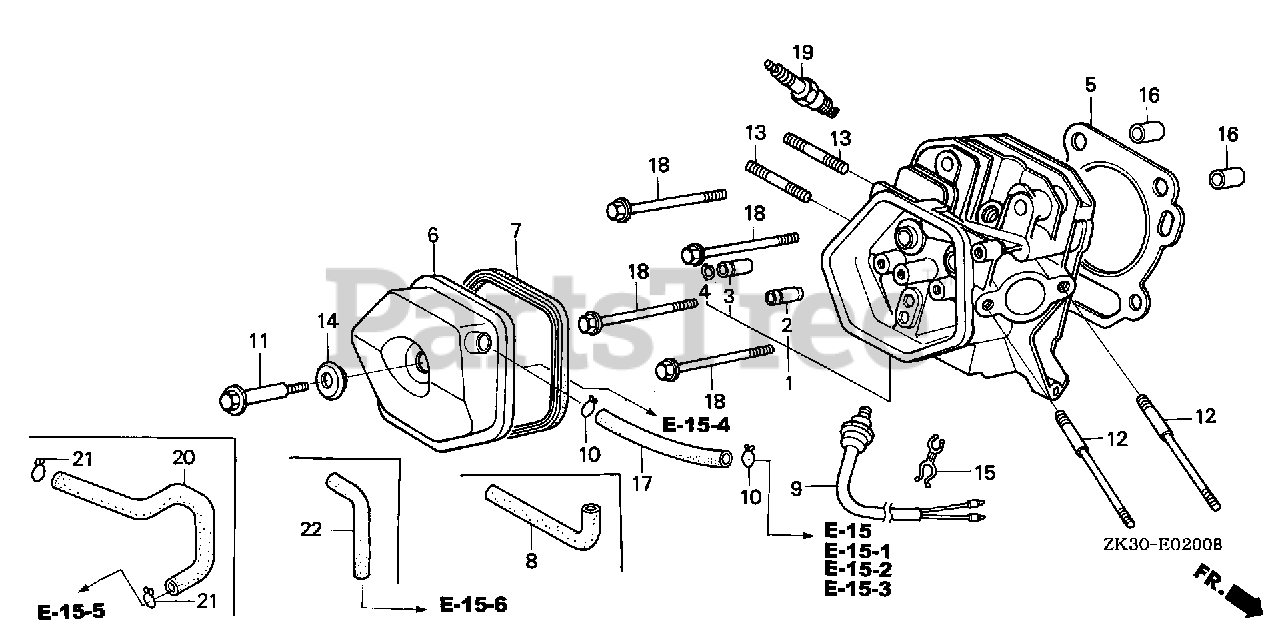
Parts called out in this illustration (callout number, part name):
1	CYLINDER HEAD
2	GUIDE, VALVE (OVER SIZE)
3	GUIDE, EX. VALVE (OVER SIZE)
4	CLIP, VALVE GUIDE
5	GASKET, CYLINDER HEAD
6	COVER, HEAD
6	COVER, HEAD (BREATHER TUBE JOINT)
7	GASKET, HEAD COVER
11	BOLT, HEAD COVER
12	BOLT, STUD (8X131.5)
13	BOLT, STUD (8X47)
13	BOLT, STUD (8X32)
14	WASHER, HEAD COVER
16	PIN, DOWEL (12X20)
17	BULK HOSE, VACUUM (11X1000) (11X105)
18	BOLT, FLANGE (10X80)
19	SPARK PLUG (BPR5ES) (NGK)
19	SPARK PLUG (W16EPR-U) (DENSO)
19	SPARK PLUG (BPR6ES) (NGK)
19	SPARK PLUG (W20EPR-U) (DENSO)
